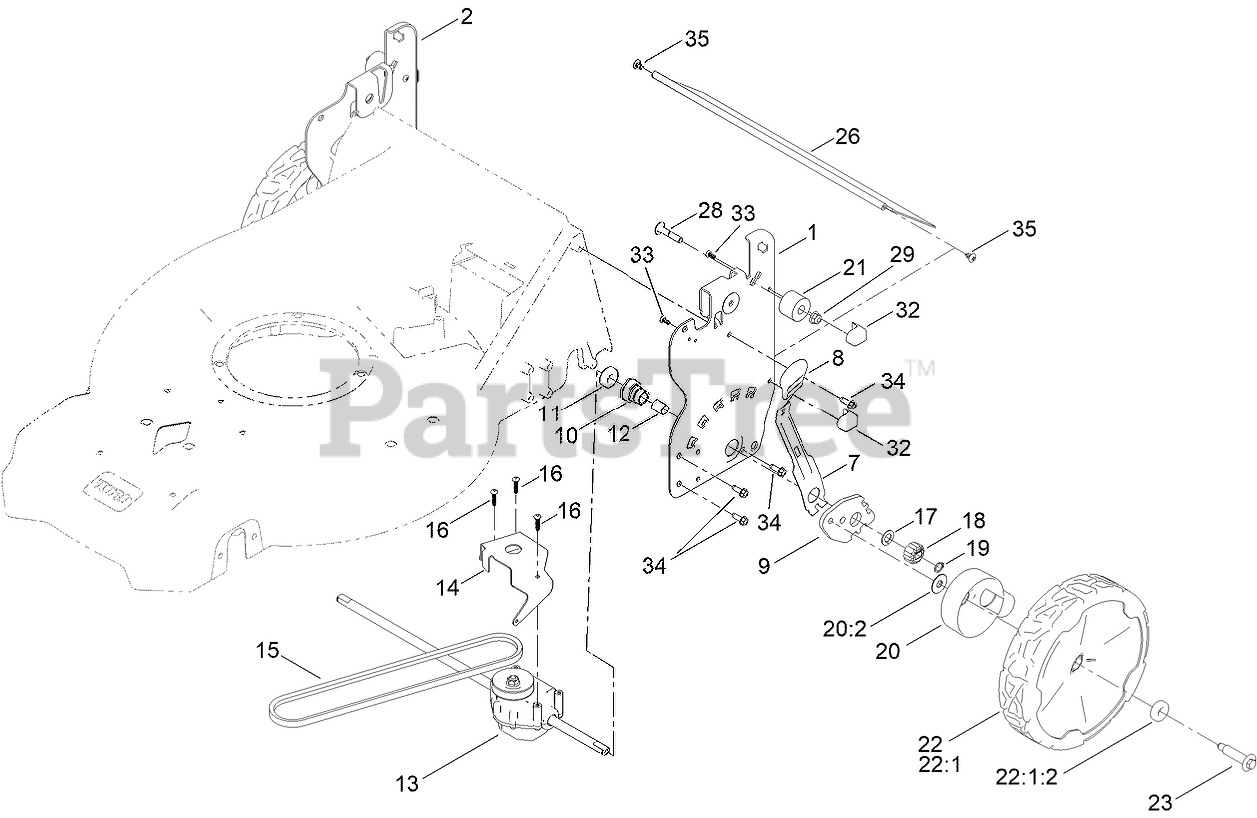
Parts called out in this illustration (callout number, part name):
1	PLATE-HOC, LH
2	PLATE-HOC, RH (ISO)
7	ARM-SPRING
8	KNOB-HOC
9	ARM-PIVOT, REAR
10	RETAINER-BUSHING, HOC
11	BEARING-WHEEL
12	BUSHING-SLEEVE
13	TRANSMISSION-RWD, 5.25:1
14	BRACKET-TRANS, RWD HI
15	BELT-V
16	SCREW-PLASTITE
17	WASHER-THRUST
18	GEAR-PINION, 15T
19	RING-RETAINING
20	ASM-COVER, GEAR
20:2	WASHER-STEPPED
21	BUMPER-ISOLATOR
22	ASM-9.65" WHEEL, GEARED
22:1	ASM-WHEEL, 9.65" (BEARINGS)
22:1:2	BEARING-WHEEL
23	WHEEL BOLT
26	SHIELD-TRAILING
28	SCREW-CARR-SPCL
29	NUT-HF, NI
32	PAD-SMART STOW
33	SCREW-PLASTITE
34	SCREW-HWHTF
35	SCREW-PTH
